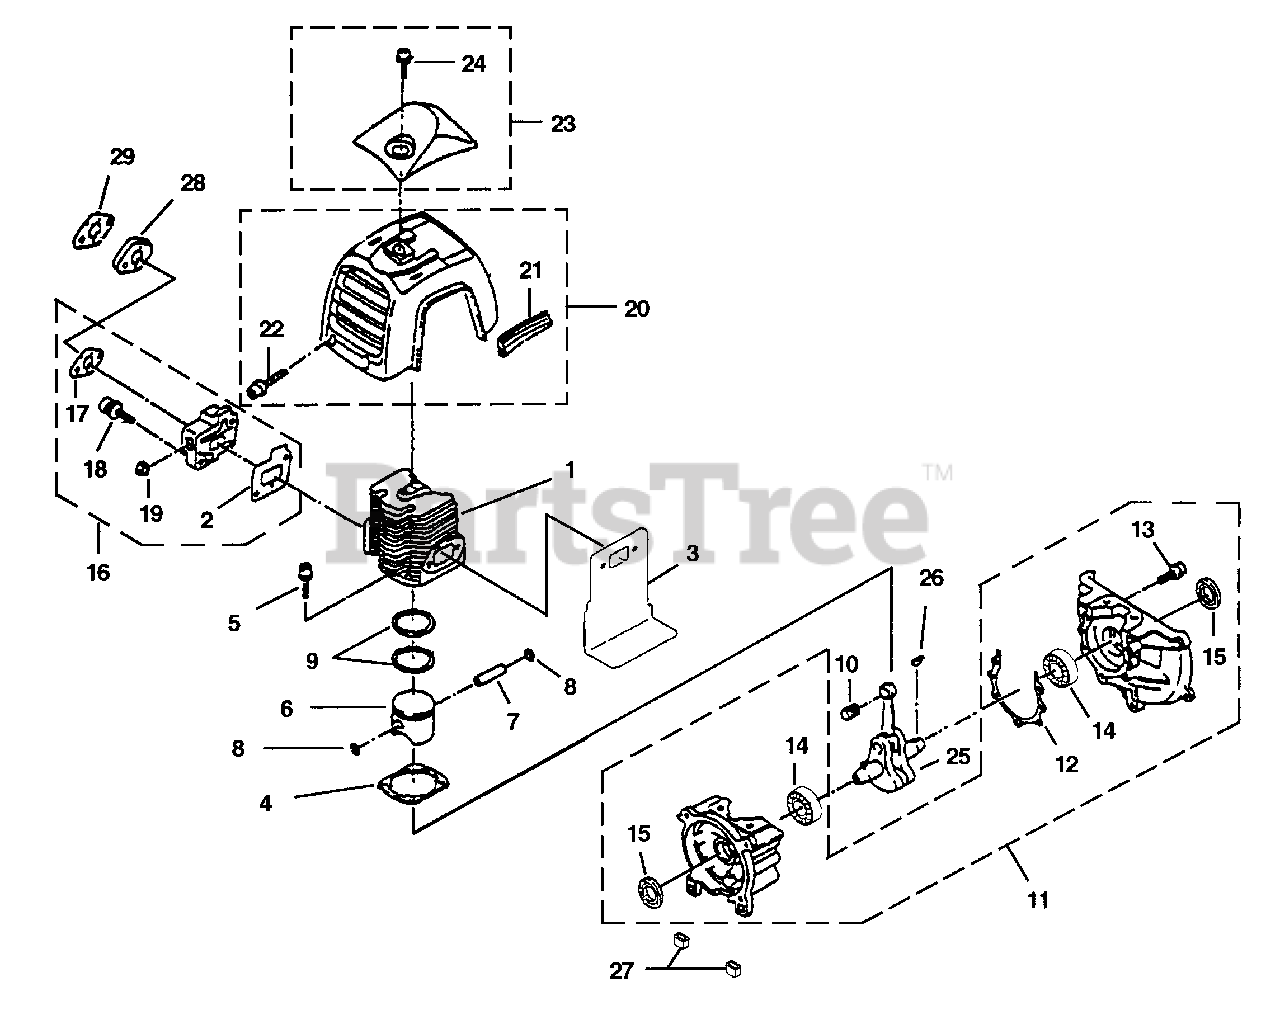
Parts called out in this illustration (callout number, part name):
1	CYLINDER ASSEMBLY
2	GASKET-Heat Dam
3	GASKET-Muffler
4	GASKET-Cylinder
5	SCREW-Socket HD (M5 x 18 SW)
6	PISTON ASSEMBLY
7	PIN-Piston
8	RING-Retaining
9	RINGS-Piston
10	BEARING-Wrist Pin
11	CRANKCASE ASSEMBLY
12	GASKET-Crankcase
13	SCREW (M5 x 25)
14	BALL BEARING
15	OIL SEAL
16	HEAT DAM ASSEMBLY
17	GASKET-Carburetor
18	SCREW-Socket Hd (M5 x 20)
20	CYLINDER COVER
21	BUMPER, Rubber
22	SCREW (M5 X 30)
23	PLUG COVER
25	CRANKSHAFT
26	KEY-Woodruff
27	RUBBER BUMPER KIT
28	SPACER-Carburetor
29	GASKET-Carburetor
